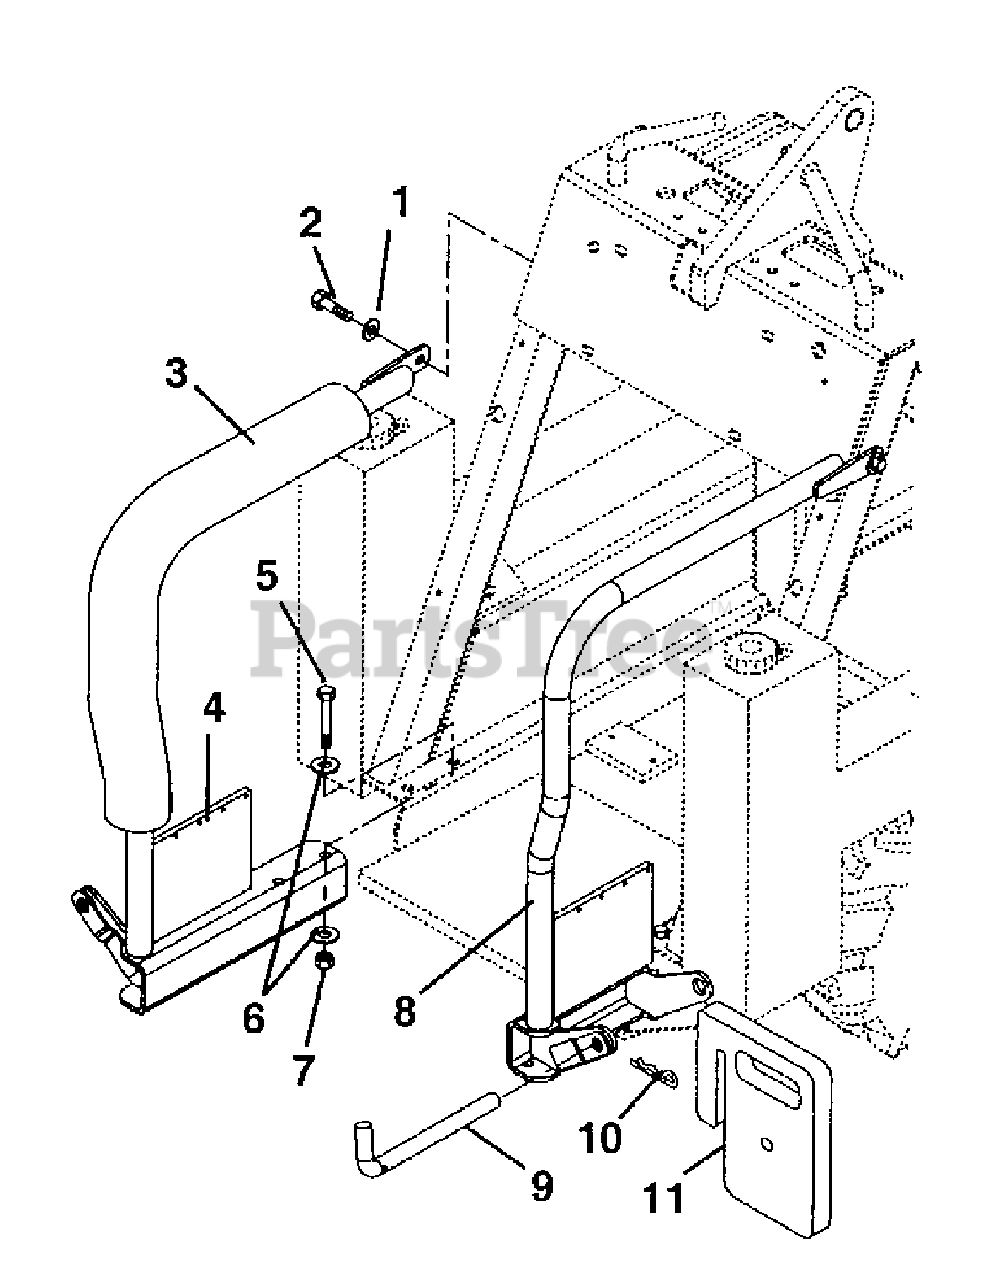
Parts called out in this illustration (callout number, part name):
1	Washer-fl-stl .38 x .875 x .083
2	Bolt, Hex 13 mm M8-1.25 x 16
3	Foam, 36" long
4	Weldment, weight - LH
5	Bolt, Hex 19mm M12-1.75 x 110
6	Washer-fl-stl .531 x 1.06 x .095
7	Nut, hex 19mm M12-1.75 nyloc
8	Weldment, weight - RH
9	Pin, weight
10	Pin-hair-ext .12 x .31 x 2.37
11	Weight, rear
